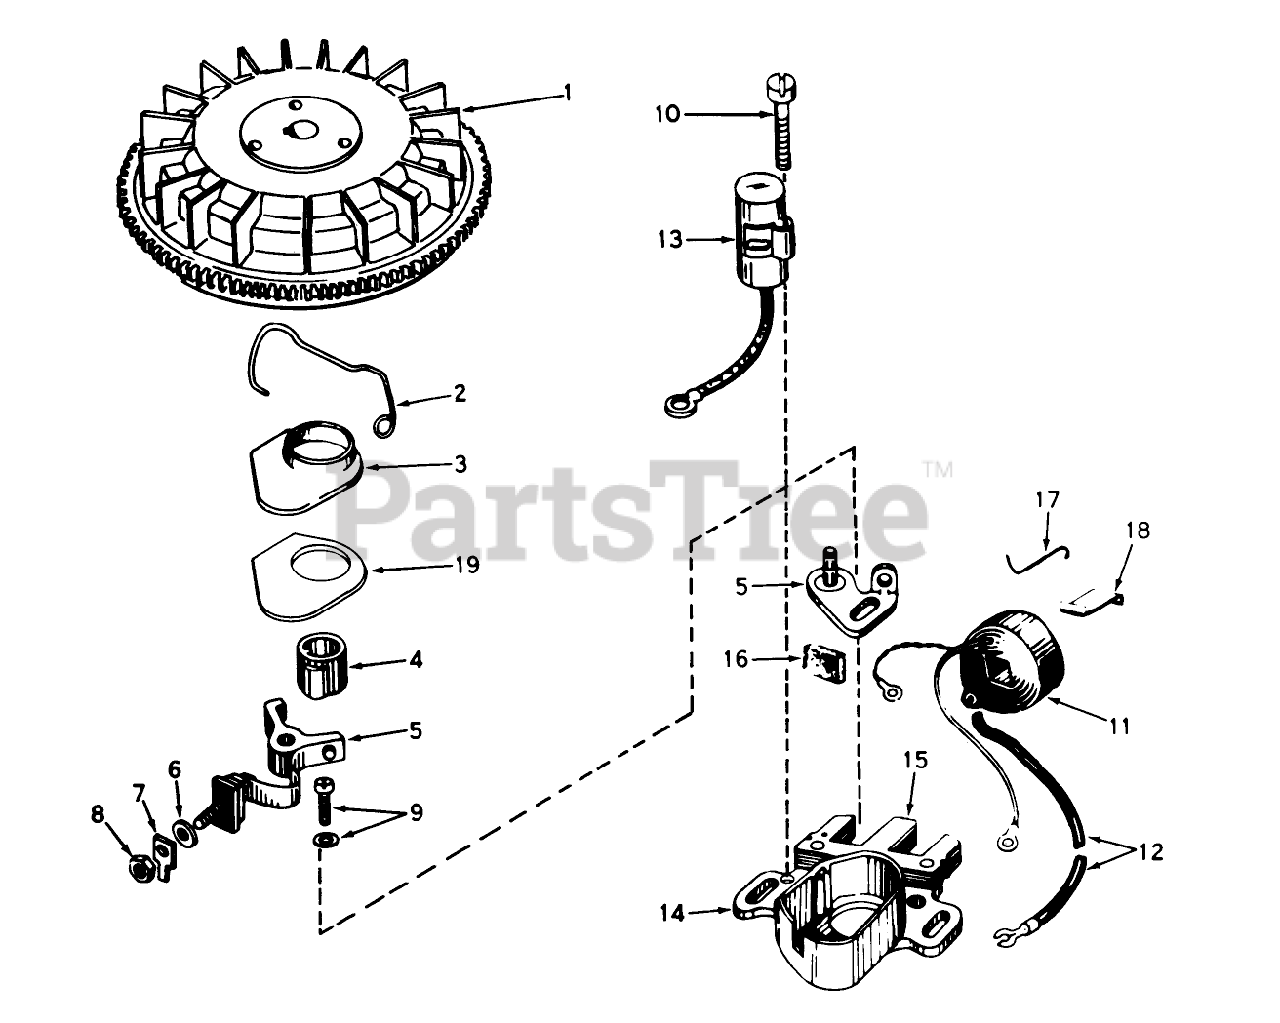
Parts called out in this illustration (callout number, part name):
1	FIywheel
2	Spring Breaker Box
3	Cover, Dust
4	Cam-Breaker
5	Breaker Assy.
6	Washer
7	Terminal
8	DECAL
9	Breaker Screw
10	Condenser Screw
11	Coil Assy. (Incl. No. 12)
12	Wire, Lead
13	Condenser
14	Core Plate
15	Stator Assy., (Incl. Nos. 2, 3, 5 thru 14 16 thru 19)
16	Felt,Cam Wiper
17	Clip, Coil
18	Spring Coil Wedge
19	Gasket Dust Cover
